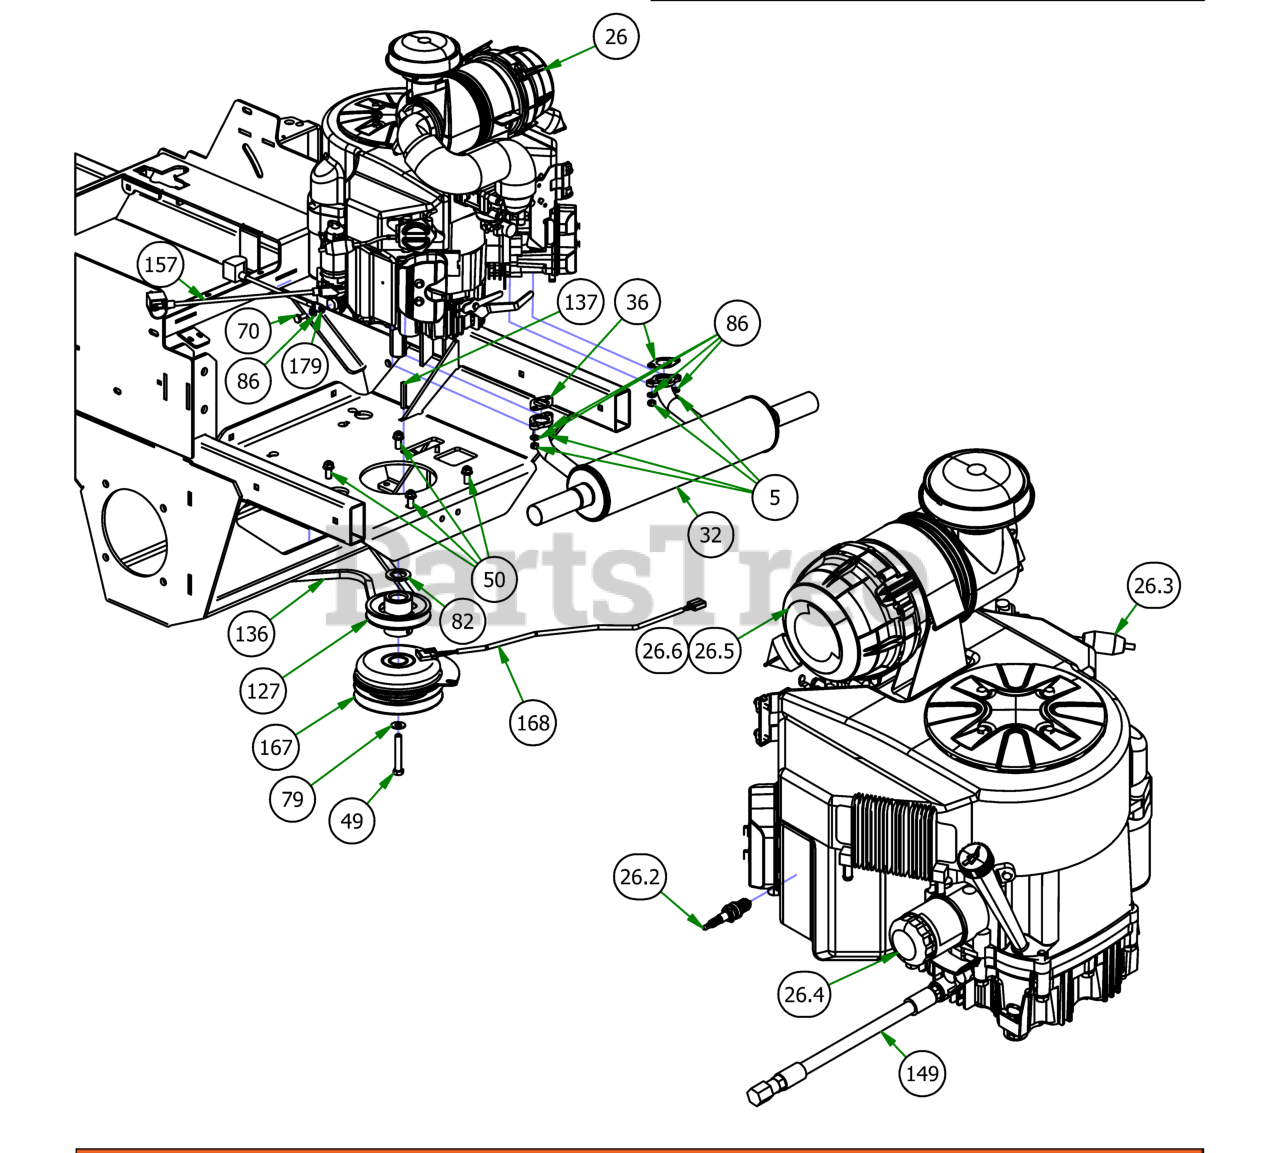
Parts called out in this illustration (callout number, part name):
5	M8-1.25 Zinc Nut
10	3/8-16 HEX SERRATED FLANGE NUT HARD/ZINC
26	Kawasaki FX850 Engine
26.2	Spark Plug - Kawasaki
26.3	Universal Inline Fuel Filter
26.4	Oil Filter
26.5	Canister Air Filter- Outer
26.6	Canister Air Filter- Inner
32	2019 Rebel/Rogue Kawasaki 850 Muffler
36	Exhaust Gasket
49	7/16-20 x 2 3/4 Hex C/S GR 8 Yellow Zinc
50	3/8 x 1 1/8 bolt
70	M8x1.20x20MM Hex head bolt
72	3/8-16 X 1-1/2 HEX CAP SCREW (GR.5) ZINC
79	3/8 FLAT WASHER USS (1" OD) ZINC
82	1 1/8" Flat Spacer
86	5/16" Lock Washer
127	4 3/4 Motor Pulley
136	2019 Rebel Pump Belt
137	1/4 x 2 Square key Stock
149	Kawasaki Oil Drain
157	14" Red Battery Cable-Base Outlaw
167	Clutch Assembly
168	Clutch Pigtail
169	2019 Rebel Frame - Powdercoated
179	Starter Cable
